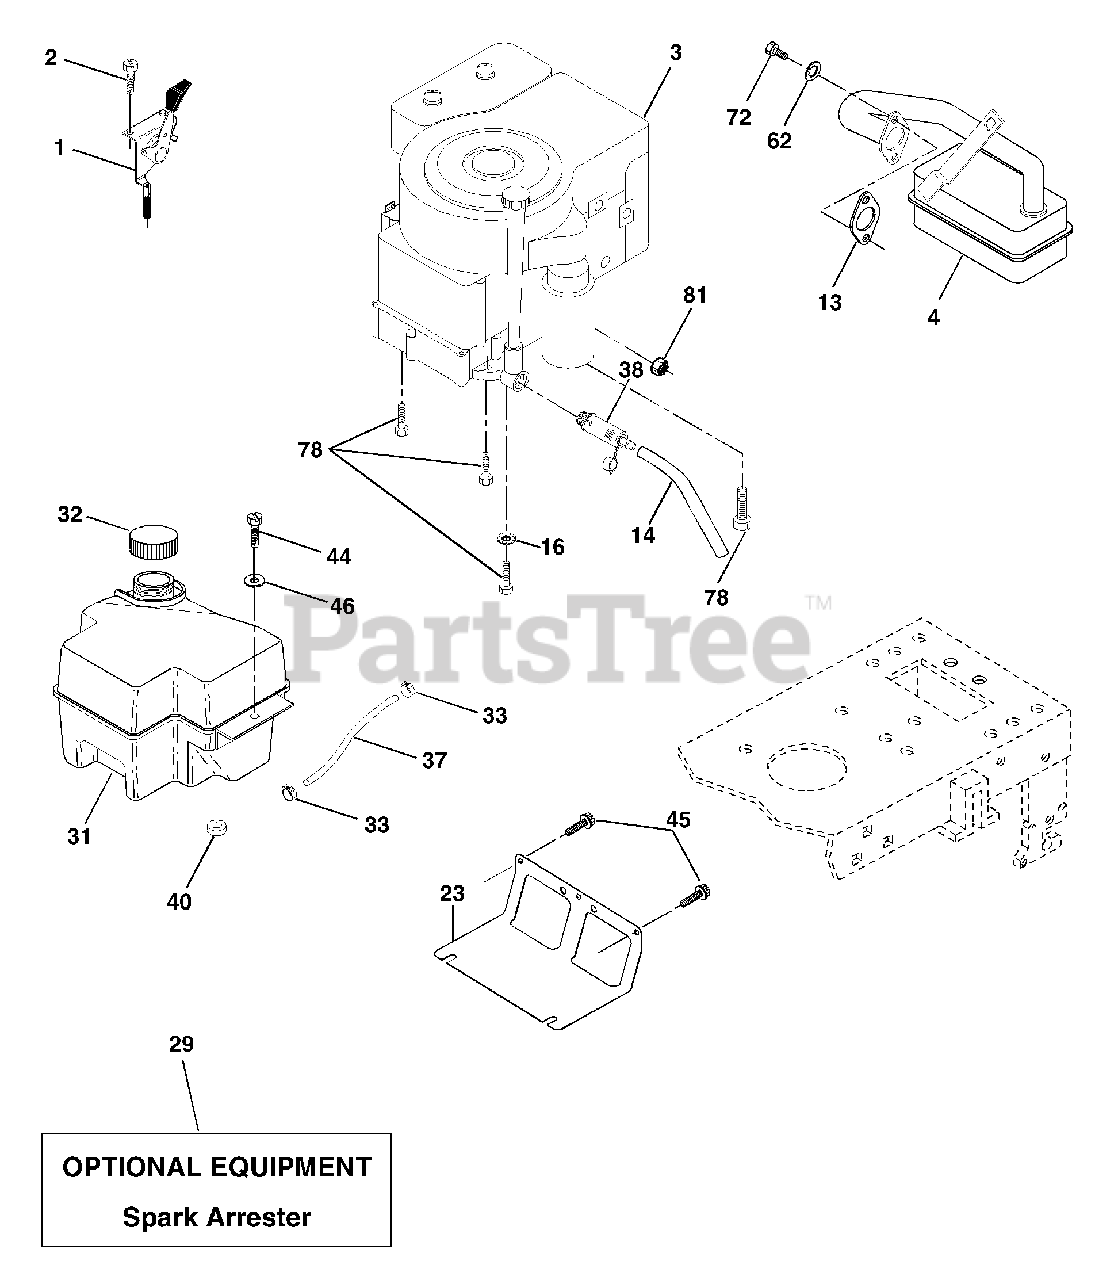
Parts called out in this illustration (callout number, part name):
1	Control Th/ch
2	Screw Hex Thd Cut 1/4-20x5/8 T
4	Muffler
13	Gasket Eng 1 313 Id Tin Plated
14	Tube Drain Oil Easy
16	Washer Lock Ext Tooth 3/8
23	Shield Browning
29	Kit Spark Arrestor (Flat Scrn)
31	Tank Fuel Front 1 25
32	Cap Asm Fuel
33	Clamp Hose Blk
37	Line Fuel 20"
38	Plug Drain Oil Easy
40	Bushing Snap Nyl Blk Fuel Line
44	Screw Hexwsh Thdrol 1/4-20 x 3/4
45	Screw Hex Wsh Thdrol 3/8-16
46	Washer 9/32 x 7/8 x 16 ga
62	Washer Lock Hvy Hlcl Spr 5/16
72	Screw Hexhd Cap 5/16-18 x 3/4
78	Screw 3/8-16 x 1-1/4
81	Nut Keps Hex 1/4-20 UNC
